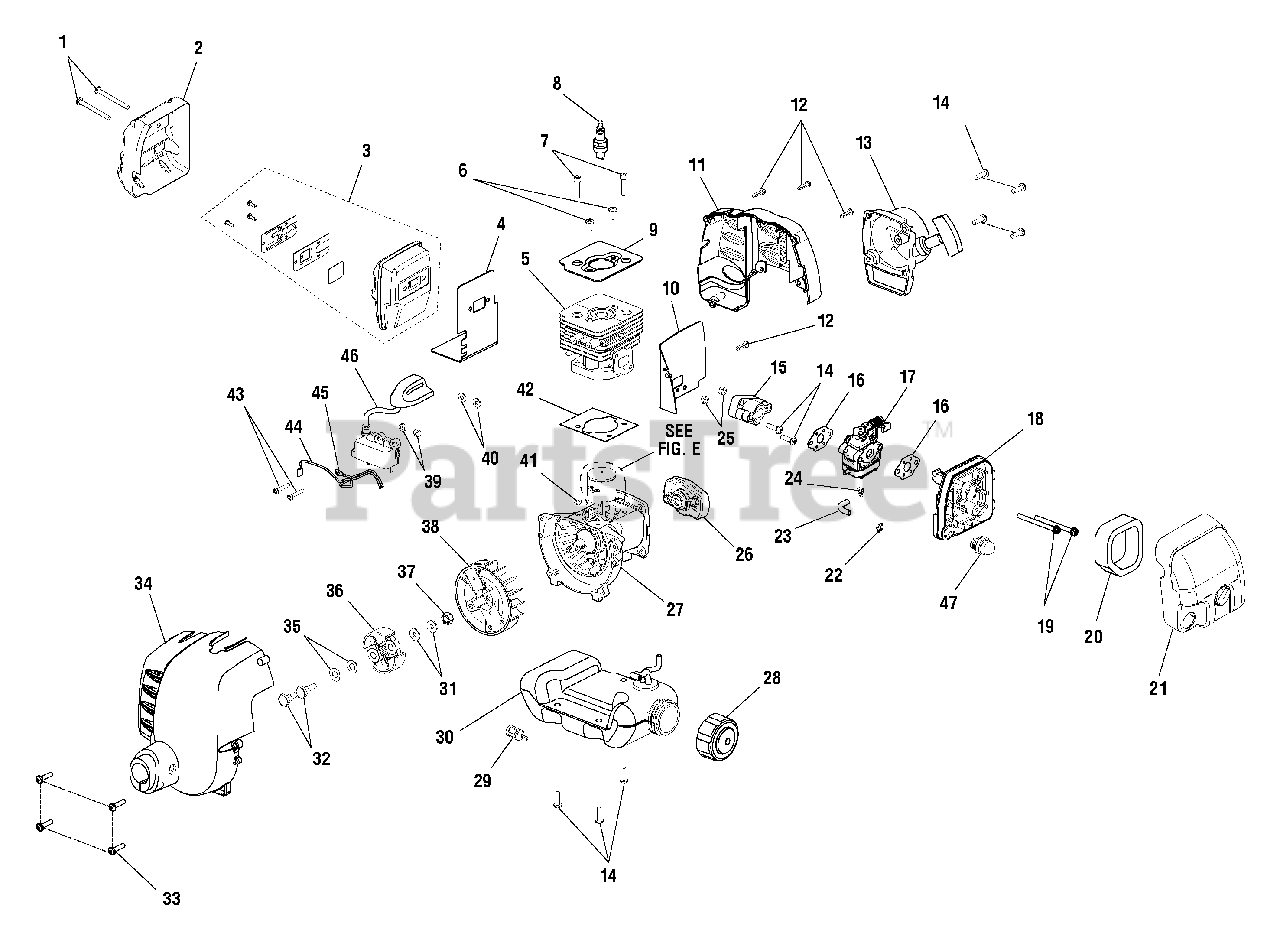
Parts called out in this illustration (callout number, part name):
1	SCREW (M5 X 50 mm TORX SLOTTED RECESSED PAN HD.)
2	HEAT SHIELD
3	MUFFLER ASSEMBLY
4	MUFFLER GASKET
5	CYLINDER
6	SCREW (M5 X 10 in. TORX RECESSED PAN HD.)
7	SCREW (M5 X 22 mm SOCKET HD.)
8	SPARK PLUG
9	CYLINDER PLATE
10	INSULATOR GASKET
11	ENGINE HOUSING, REAR
12	SCREW (M4 X 16 mm TORX RECESSED PAN HD.)
13	STARTER RECOIL ASSEMBLY
14	SCREW (M5 X 16 mm Torx SLOTTED RECESSED PAN HD.)
15	HEAT DAM INSULATOR
16	CARBURETOR GASKET
17	CARBURETOR ASSEMBLY
18	FILTER HOUSING ASSEMBLY
19	SCREW (M5 X 60 mm, SLOTTED RECESSED PAN HD. MACHINE)
21	COVER ASSEMBLY
22	HOSE CLIP
23	FUEL LINE
24	HOSE CLIP
25	NUT (M5 x .8 mm)
26	PULLEY ASSEMBLY
27	CRANKCASE ASSEMBLY
28	FUEL CAP ASSEMBLY
29	FUEL FILTER
30	FUEL TANK ASSEMBLY
32	CLUTCH SCREW
33	SCREW (M5 X 20 mm TORX SLOTTED RECESSED PAN HD.)
34	FRONT HOUSING ASSEMBLY
35	CURVED WASHER
36	CLUTCH ASSEMBLY
37	ROTOR NUT
39	IGNITION COIL SPACER
40	WASHER (3/16 x 3/64)
41	WOODRUFF KEY (10 mm X 3 mm)
43	SCREW (M4 X 22 mm TORX SLOTTED RECESSED PAN HD.)
44	LEAD ASSEMBLY, BLACK
45	LEAD ASSEMBLY, RED
46	COIL BOOT ASSEMBLY
47	PRIMER ASSEMBLY
